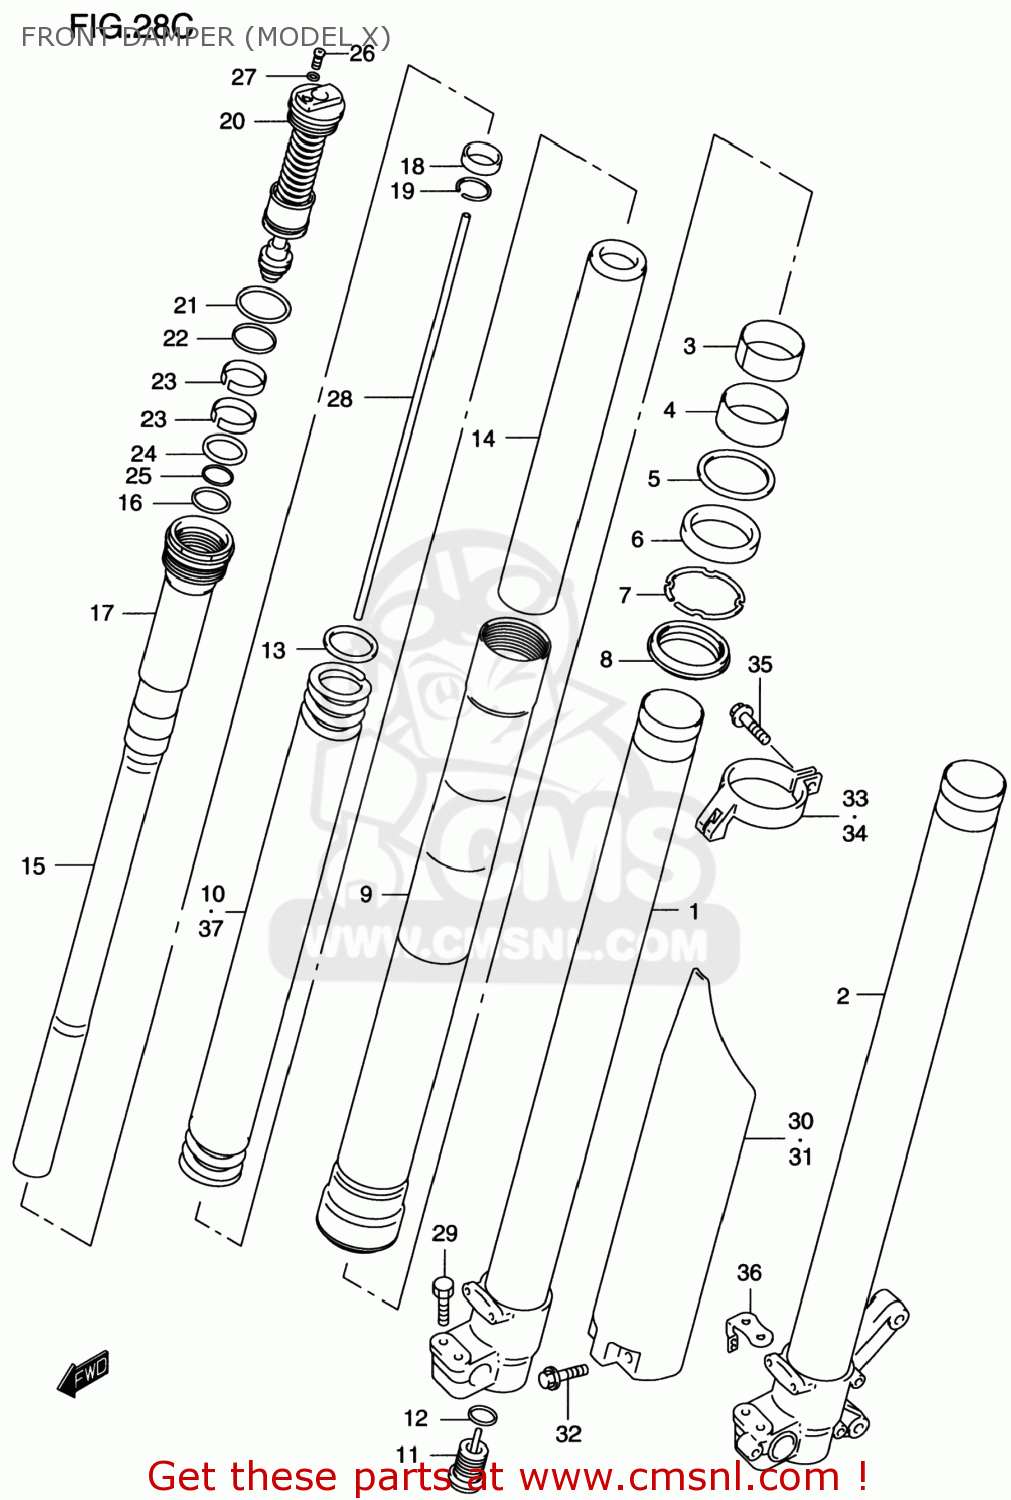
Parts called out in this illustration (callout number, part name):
1	TUBE,INNER,RIGHT
2	TUBE,INNER,L
3	BUSH,SLIDE
4	BUSH,GUIDE
5	SPACER,SEAL
6	SEAL,OIL
7	RING,STOPPER
8	SEAL,DUST
9	TUBE,OUTER
10	SPRING,FR(K=0.42)
11	BOLT,CTR
12	O RING
13	STOPPER,SPRING
14	COLLAR,SPRING
15	DAMPER,CARTRIDGE
16	O-RING
17	TANK,SUB
18	VALVE,OIL LOCK
19	RING,STOPPER
20	BOLT,FORK
21	O RING
22	O RING
23	BUSH,FORK BOLT SLIDE
24	O RING
25	O RING,LWR
26	BOLT,PLUG
27	O RING,PLUG
28	ROD,PUSH
29	BOLT,HANDLE HOLDER(8X35)
30	PROTECTOR FORK,R
31	PROTECTOR,FORK,L
32	BOLT,PROTECTOR(6X10)
33	GUIDE,PROTECTOR,R
34	GUIDE,PROTECTOR,L
35	BOLT
36	STOPPER,BRAKE HOSE,L
37	SPRING,FR(K=0.40)
